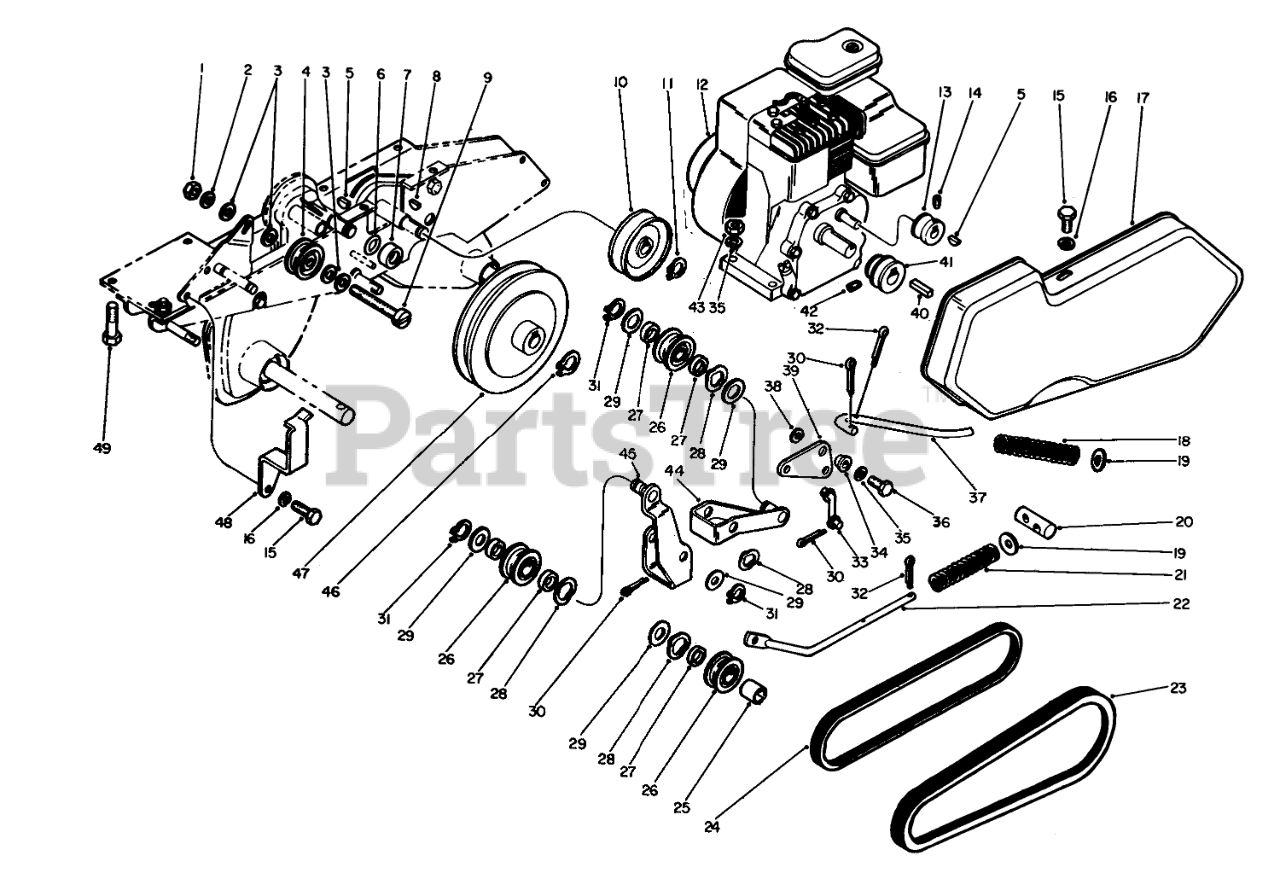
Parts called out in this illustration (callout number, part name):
1	NUT-HEX
2	WASHER-LOCK
3	WASHER-FLAT
4	Idler Pulley
5	KEY-WOODRUFF
6	O-Ring
7	Seal Cup
8	KEY-WOODRUFF
9	Machine Screw
10	Pulley-Tines
11	Retaining Ring
12	Engine
13	Camshaft Pulley
14	SCREW-SET, HSH
15	SCREW-HH
16	WASHER-LOCK
17	Belt Guard w/Decal
18	Spring-Tine Drive
19	Washer
20	Swivel
21	Spring-Traction Drive
22	Control Rod
23	Tine Drive Belt
24	Traction Drive Belt
25	Spacer-Idler
26	Idler Pulley
27	Spacer
28	Wave Washer
29	Washer
30	PIN-COTTER
31	RING-SNAP, EXTERNAL
32	PIN-COTTER
33	Link
34	Pivot Bushing
35	WASHER-LOCK
36	SCREW-HH
37	Control Rod
38	WASHER-FLAT
39	Bellcrank
40	KEY-SQUARE
41	Engine Pulley
42	SCREW-SET, HSH
43	NUT-HEX
44	Tine Drive Idler
45	Traction Drive Idler
46	Retaining Ring
47	Pulley-Traction
48	Belt Guide
49	SCREW-HH
